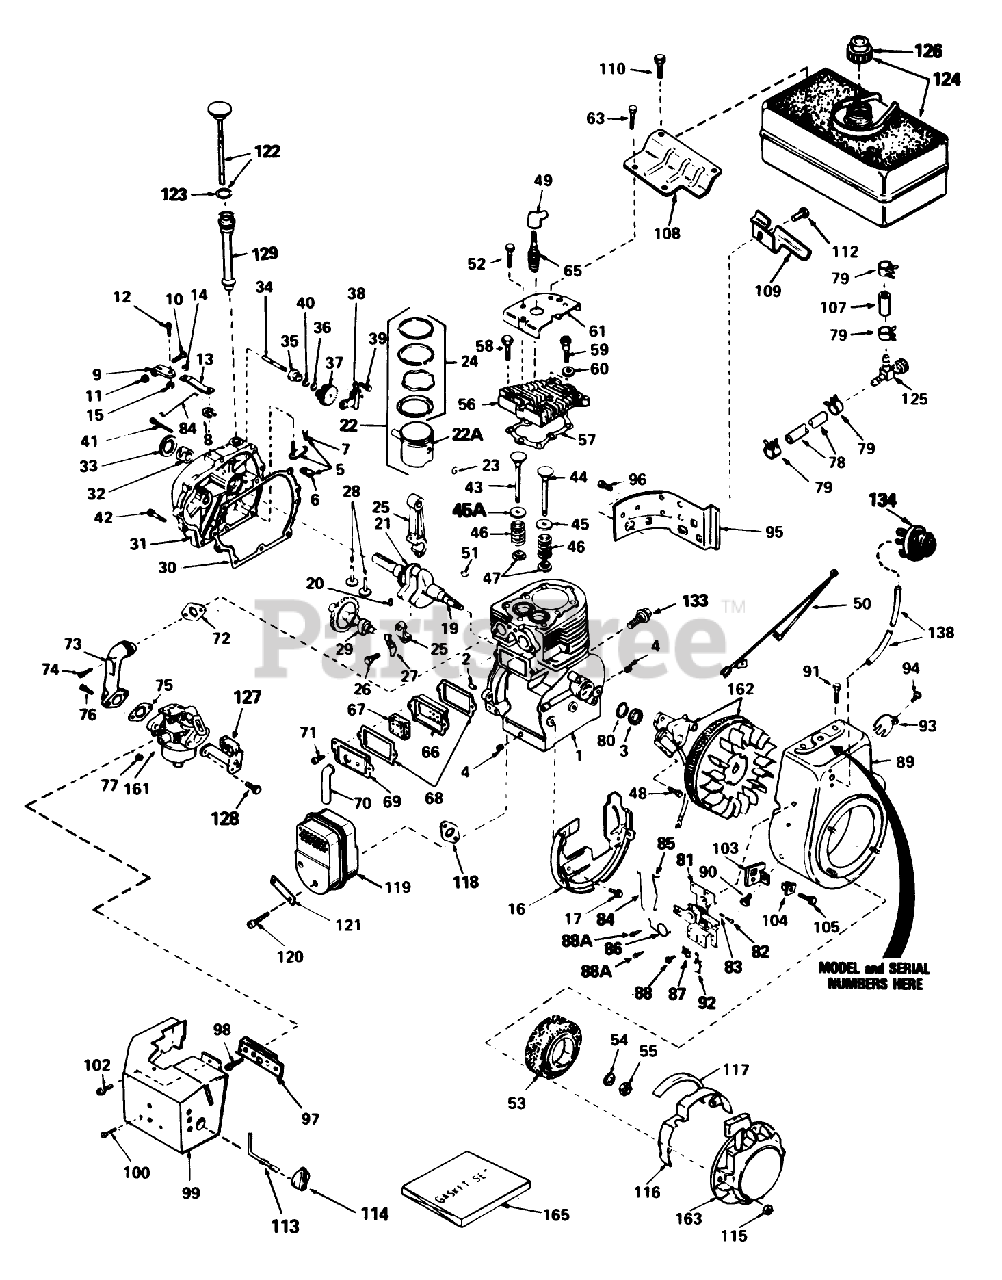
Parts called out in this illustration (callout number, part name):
1	Cylinder Assembly (Incl.Ref. #2, 3, 4 45A)
2	Pin-Dowel
3	Oil Seal
4	Plug-Drain, Oil (SQH 1/4-18)
5	Rod, Governor (Incl. Nos.62 63)
6	Yoke-Governor
7	Screw (6-40x5/16)
8	Ring-Retaining
9	Clamp-Lever, Governor
10	Screw
11	Nut-Lock
12	Screw
13	Lever-Governor
14	Washer-Lock
15	Nut-Lock
16	Baffle Blower Housing
17	Screw (1/4-20x19/32)
19	Crankshaft Assy. (Incl. Nos. 20 21)
20	Pin, Groove
21	Gear, Crankshaft
22	Piston, Pin Ring Assy.(Std.) (Incl. Ref. #24A, 25 26)
22	Piston, Pin Ring Assy. (.010 oversize) (Incl. Ref. #24A, 25 26)
22	Piston, Pin Ring Assy. (.020 oversize) (Incl. Ref. #24A, 25 26)
22A	Piston Pin Assy. (Std.) (Incl. Ref. #26)
22A	Piston Pin Assy. (.010 oversize) (Incl. Ref. #26)
22A	Piston Pin Assy. (.020 oversize) (Incl. Ref. #26)
24	Ring Set (Std.)
24	Ring Set (.010" OS)
24	Ring Set (.020" OS)
25	Rod Assy., Connecting (Incl. Nos. 10 18)
26	Bolt, Connecting Rod
27	Dipper-Oil
28	Lifter-Valve
29	Camshaft (Mech. Comp. Release)
30	Gasket, Cylinder Cover (Incl. Ref. #41)
31	Cover, Cylinder (Incl. Ref. #32, 33 34)
32	Bushing, Crankshaft
33	Seal, Oil
34	Shaft-Governor
35	Spool-Governor
36	Ring-Retaining
37	Governor Gear ASM
38	Bracket-Gear, Governor
39	Screw (10-24x1/2)
40	Washer-Flat
41	Screw (1/4-20x1-3/16)
42	Screw (1/4-20x1-11/16)
43	Valve, Intake (Std.) (Incl. Ref. #58)
43	Valve, Intake (1/32" oversize) (Incl. Ref. #58)
44	Valve, Exhaust (Standard)(Incl. No. 9)
44	Valve, Exhaust (1/32" oversize)(Incl. No. 9)
45	Cap-Spring, Valve
45A	Seal-Intake Valve
46	Spring-Valve
47	Keeper-Spring, Valve
48	Screw
49	Cover-Spark Plug
50	Wire, Ground
51	Key-Flywheel
52	Screw (1/4-20 X 5/8)
53	Hub Screen Assy., Starter
54	Washer-Belleville
56	Head Cylinder
57	Gasket-Cylinder Head
58	Screw (5/16-18x1-1/2)
59	Screw (5/16-18x1-25/32)
60	Washer-Flat
61	Cover, Cylinder Head
63	Screw
65	Plug, Spark (J17LM or equiv.)
65	Plug, Spark (Champion RCJ-8)
66	Body-Breather
67	Element-Breather
68	Gasket-Breather
69	Cover-Valve
70	Tube-Breather
71	Screw
72	Gasket-Intake
73	Pipe-Intake
74	Screw (T-30, 5/16-18x1-3/32)
75	Gasket-Carburetor To Intake Pipe
76	Screw (1/4-28x1)
77	Nut and Lock Washer (1/4-28)
78	Line-Fuel
79	Clamp-Line, Fuel
80	Gasket Stator
81	Control Assy., Remote Speed (Incl. Ref. #90 thru 93)
82	Screw
83	Spring-Compression
84	Link-Governor
85	Link-Throttle
86	Spring-Throttle
87	Conduit
88	Screw (10-32 x 3/8)
88A	Screw (10-32 x 1/2)
89	Housing, Blower
90	Screw, Hex Hd.
91	Screw (5/16-18x3/4)
92	Terminal
93	Screw
94	Screw (8-32 x 3/8)
95	Extension, Blower Housing
96	Screw
97	Bracket-Carburetor
98	Screw (8-32x27/64)
99	Cover-Carburetor
100	Screw (10-32 x 3/8)
102	Screw (10-32x1/2)
103	Bracket
104	Grommet
105	Screw
107	Line-Fuel (8.62)
108	Bracket-Tank, Fuel (Black)
109	Bracket-Tank, Fuel
110	Screw (1/4-15x7/8)
112	Screw (1/4-20x19/32)
113	Rod-Choke
114	Knob-Control
115	Nut and Lock Washer (1/4-28)
116	Guard, Starter
117	Seal, Snowguard
118	Gasket Exhaust
119	Muffler
120	Screw
121	62513 SNWTHWR W/284
122	Dipstick, Oil (Incl. Ref. #88)
123	O-Ring
124	Tank Assy., Fuel (Incl. No. 115)
125	Valve-Shut Off
126	Cap, Fuel
127	Bracket-Choke
128	Screw (10-32 x 1/2)
129	Tube Fill
133	Screw (1/4-20x1/2)
134	Primer Assy.
138	Line, Primer
161	Carburetor (Incl. Ref. #75)
162	Magneto (The complete magneto is not available as an assembly. The magneto number is shown for reference purposes only. Order component parts individually, as shown in parts list.)
163	Starter, Rewind
165	Gasket Set
